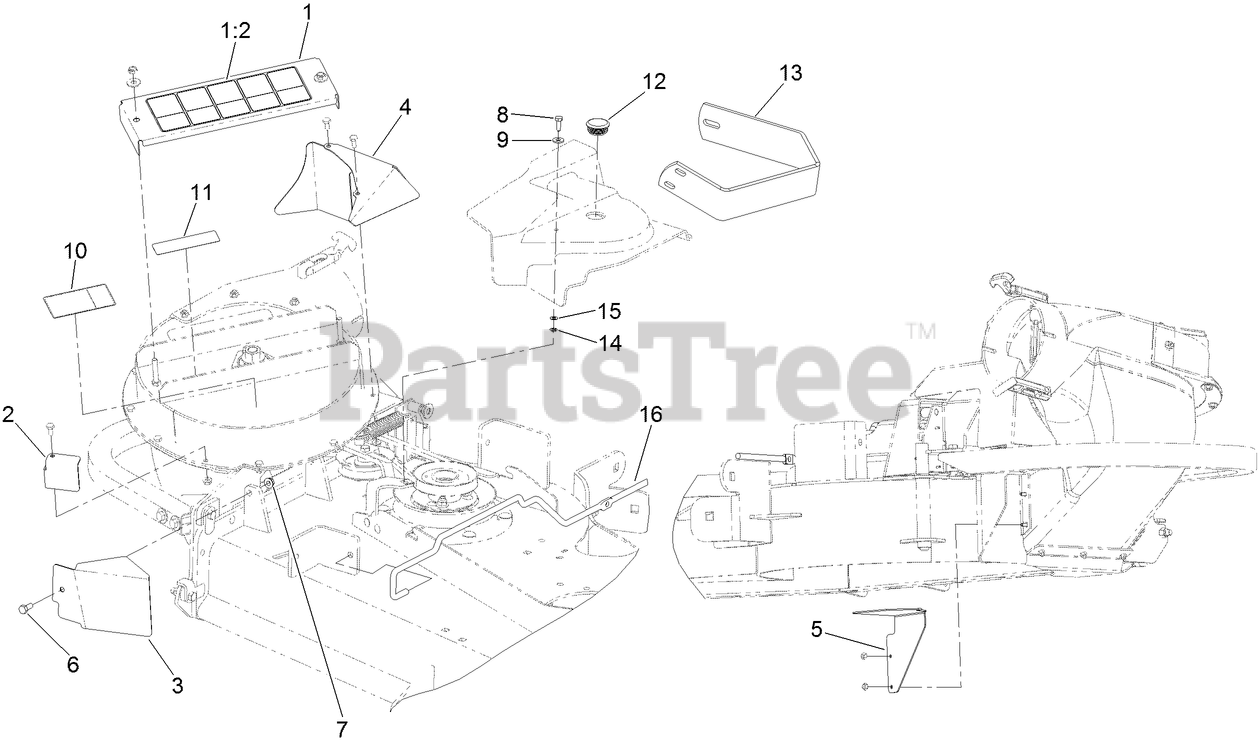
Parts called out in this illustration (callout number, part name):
1	COVER-BEARING
1:2	DECAL-DANGER
2	GUARD-LEFT
3	GUARD-FRONT
4	GUARD-BACK
5	GUARD-LOWER
6	SCREW-HH
7	NUT-HF
8	SCREW-HH
9	WASHER-FLAT
10	DECAL-WARNING
11	DECAL-MISSING, COVER
12	PLUG-PLASTIC
13	GUARD-MUFFLER
14	NUT-RETAINER
15	WASHER-FLAT
16	ROD-SUPPORT, LOWER
